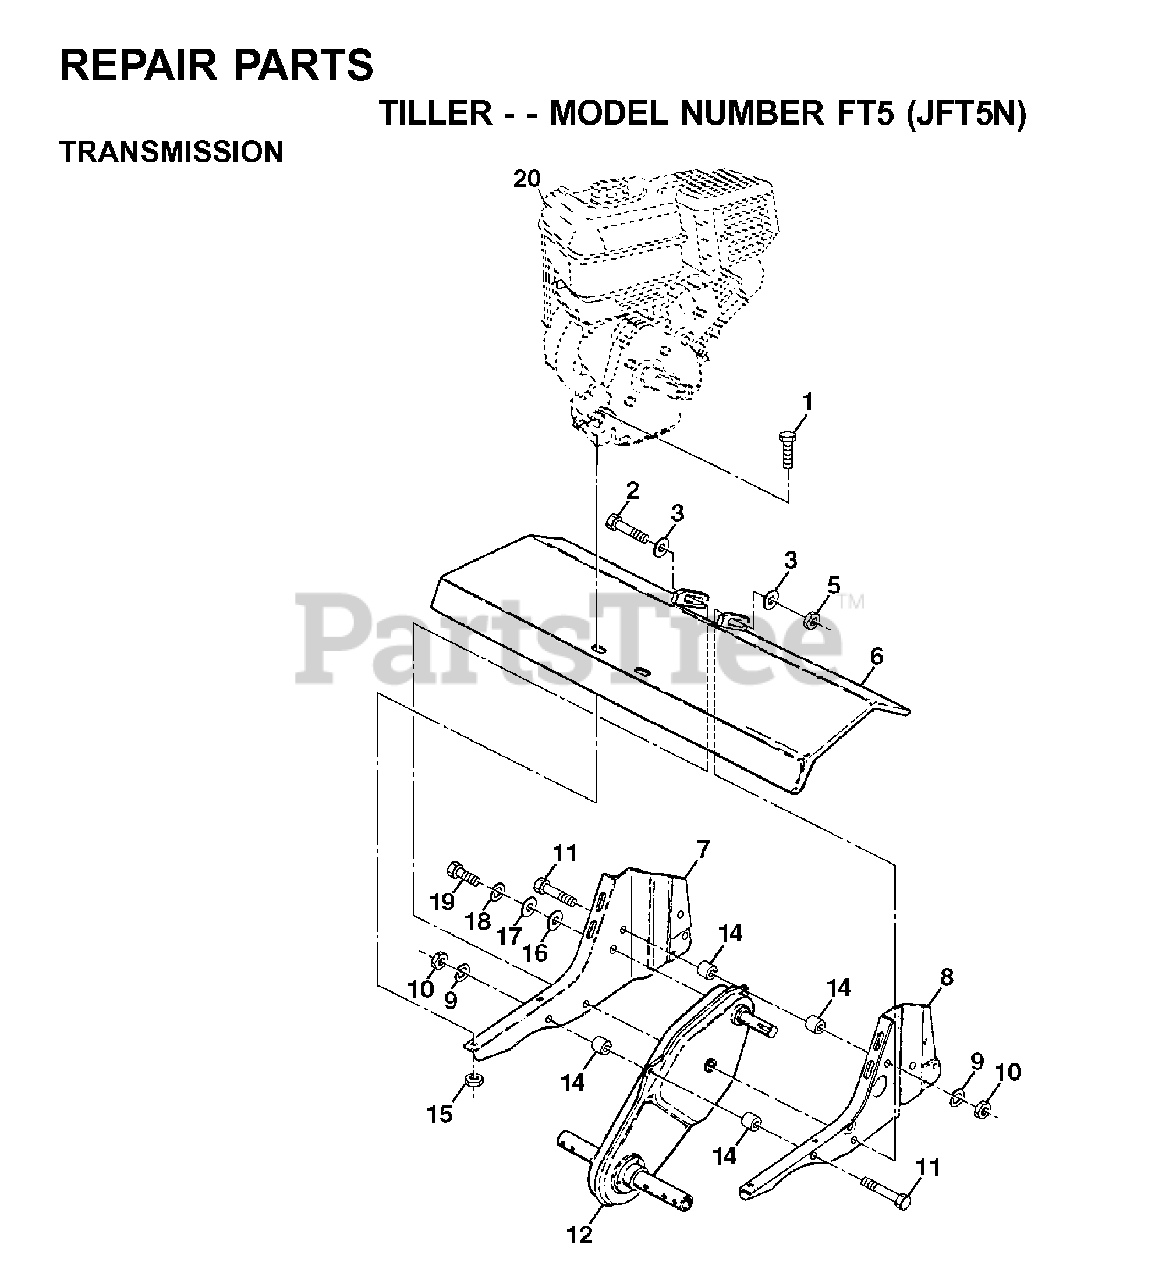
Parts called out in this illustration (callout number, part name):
1	BOLT
3	WASHER
5	NUT
9	LOCKWASHER
11	BOLT
15	LOCKNUT-FLANGE 5/16-18
18	LOCKWASHER
